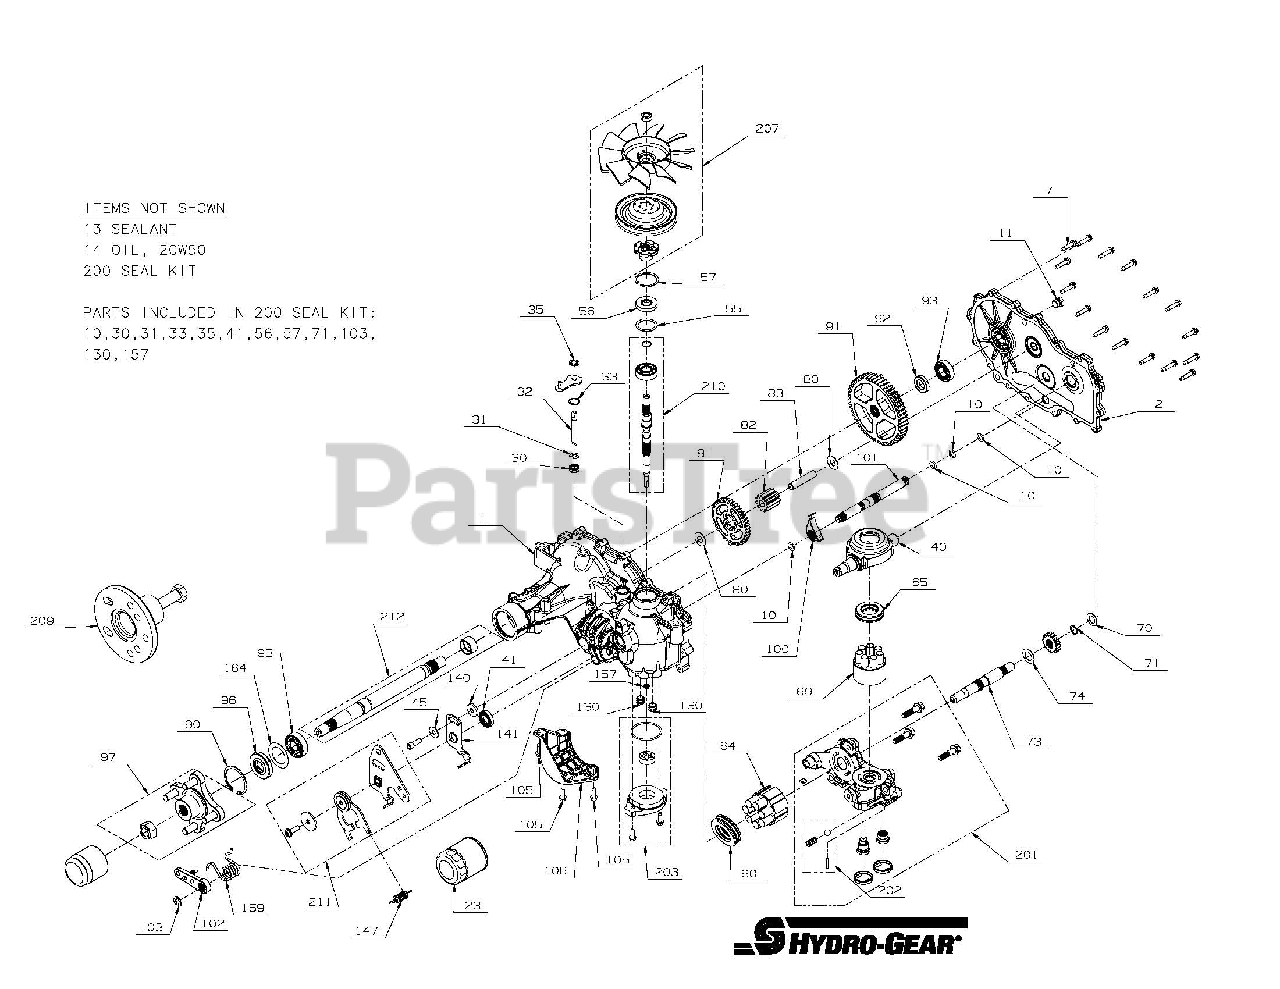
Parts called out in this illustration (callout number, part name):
1	KIT, MAIN HOUSING RH CHARGE, CONTROL
2	KIT, COVER SIDE RH
7	SCREW,HEX WASHER 1/4-20X1.125
13	SEALANT TUBE 10.1OZ.
23	OIL FILTER, TRANSMISSION
30	SEAL, LIP .375X.75X.25
31	RING. RETAINING
33	RING, RET .750
34	ARM, BYPASS
35	RING, RTNG .
40	TRUNNION, SWASHPLATE
41	SEAL, LIP 18X32X7
45	WASHER
55	WASHER 1.23X1.56X.04
56	SEAL, LIP 17X40X7
57	RING, RET 1.56 INT
60	HG THRUST BEARING (51462)
64	HG 16CC CYLINDER BLOCK (71579)
65	BEARING. THRUST 30 X 52 X 13
69	ASSY, BLOCK 7 PISTON
70	WASHER .63X1.0X.05
71	RING, RET 62 EXT
72	GEAR, 16T (STEEL)
73	SHAFT, MOTOR
74	WASHER .71 X 1.16 X .04
80	WASHER .5X1.0X.032
82	GEAR, 11T (STEEL)
83	JACK SHAFT (PIN)
90	RING, RETAINING
93	KIT, BEARING
96	SEAL, LIP
97	KIT, HUB 4 BOLT
100	PAWL, BRAKE
101	KIT, BRAKE SHAFT
102	KIT, BRAKE ARM RIGHT HAND
105	HFHCS 1/4-20X.75
106	GUARD, FILTER, RH
130	TUBE, CHARGE TRIPLE O-RING
140	SPACER
141	ARM, NEUTRAL RIGHT
142	SHCS 5/16-24X1 PATCH
147	SPRING, HYDROGEAR P/N 51833
157	KIT, GEROTOR SEAL
158	CAP, AXLE
159	SPRING, TORSION CCW
164	WASHER, 1.355 x 2.035 x .021 FLAT
200	KIT, SEAL
201	KIT CENTER SECTION RH, CHARGE
202	KIT, CHARGE RELIEF
203	KIT, CHARGE PUMP 71411
207	KIT, FAN PULLEY
209	HUB PULLER 4 BLT HYDGEAR 71459
210	INPUT SHAFT 2800 HYDGEAR 71442
211	KIT RTN BIDIRECTIONAL
212	KIT SHAFT AXLE
